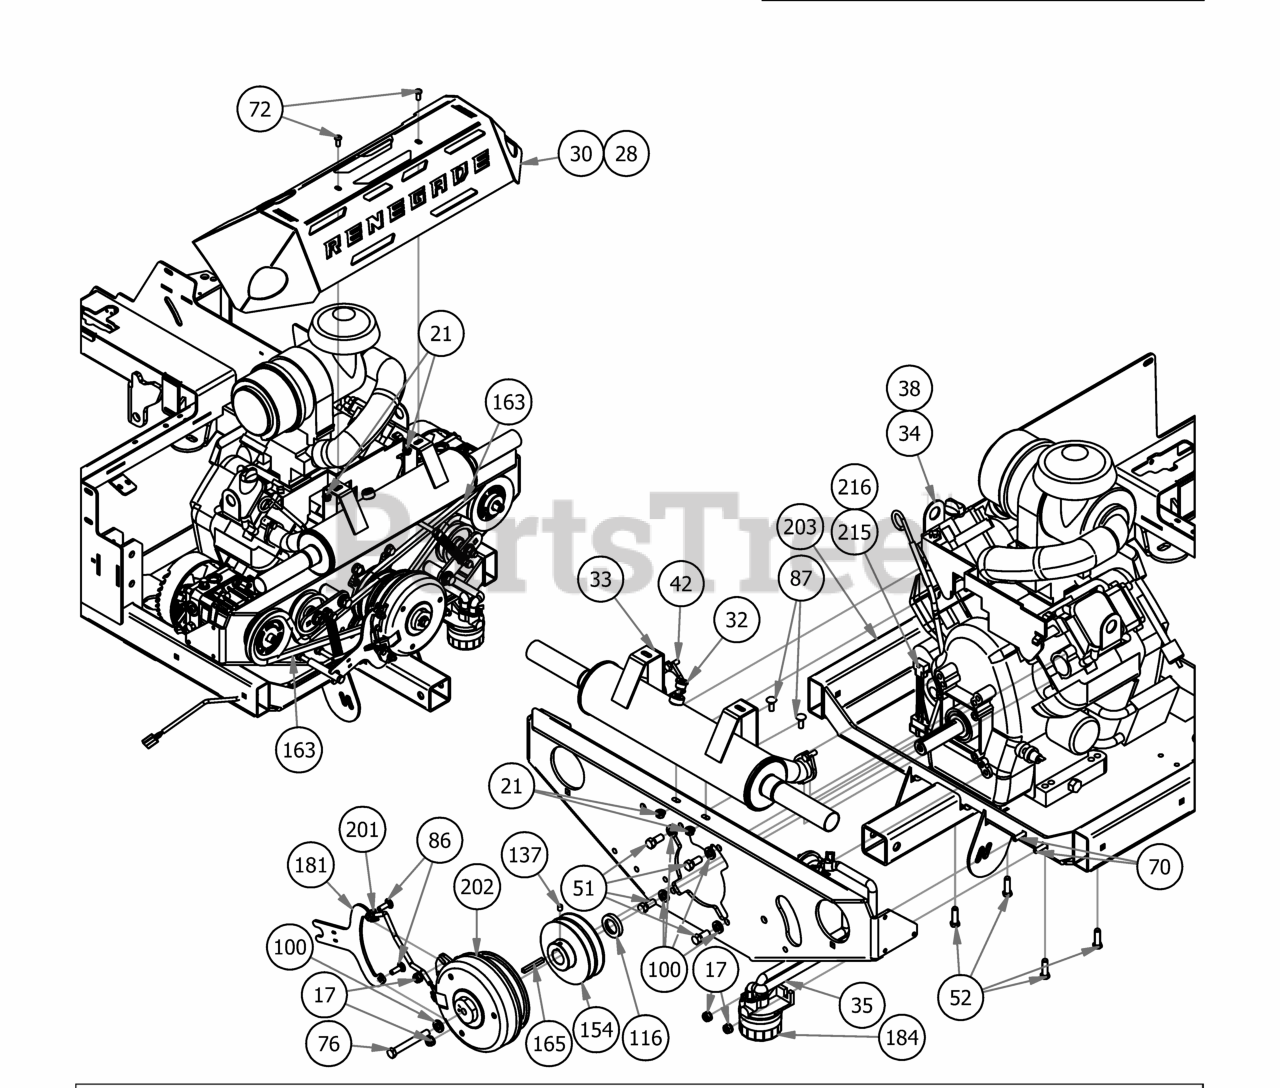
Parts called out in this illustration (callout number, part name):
17	5/16-18 Nylon Flange Nut
21	5/16" Flange Nut
28	Muffler Cover - 2019 Horizontal Gas 37 Vanguard
30	Muffler Cover - 2019 Horizontal Gas 35 Vanguard
32	O2 Sensor Plug
33	2019 Renegade Vanguard 999cc EFI Exhaust
34	Vanguard EFI 37HP 993cc Horizontal Shaft
35	Remote Oil Filter Kit For Vanguard Horizontal
38	35hp Briggs Vanguard
42	Torx Bolt-Exhaust
51	Hex Bolt - UNC (Regular Thread - Inch)
52	3/8-16 x 2 Hex/ Trilobe Horizontal Engine Bolt
70	5/16" x 1 1/4" Carriage Bolt
72	5/16" x 3/4" Button Head Bolt
76	7/16-20 x 3 1/2" Hex Head GR 8 Bolt
86	5/16" x 1" Carriage Bolt
87	5/16" x 7/8" Carriage Bolt
100	7/16" Lock Washer
116	Horizontal Engine Spacer
137	5/16-24 X 3/8 Set Screw
154	Outlaw Renegade Double V Pulley
163	2019 Renegade Pump Belt
165	1/4 x 2 Square key Stock
181	2019 Outlaw Renegade Clutch Bracket
184	Briggs Oil Filter
201	Clutch Pigtail
202	Clutch for Diesel/Vanguard
203	2019 Horizontal Gas Frame
215	2019 Harness Adaptor - 36 Vanguard Carberated
216	2019 Harness Adaptor - Vanguard 37 EFI Vert/Horiz
